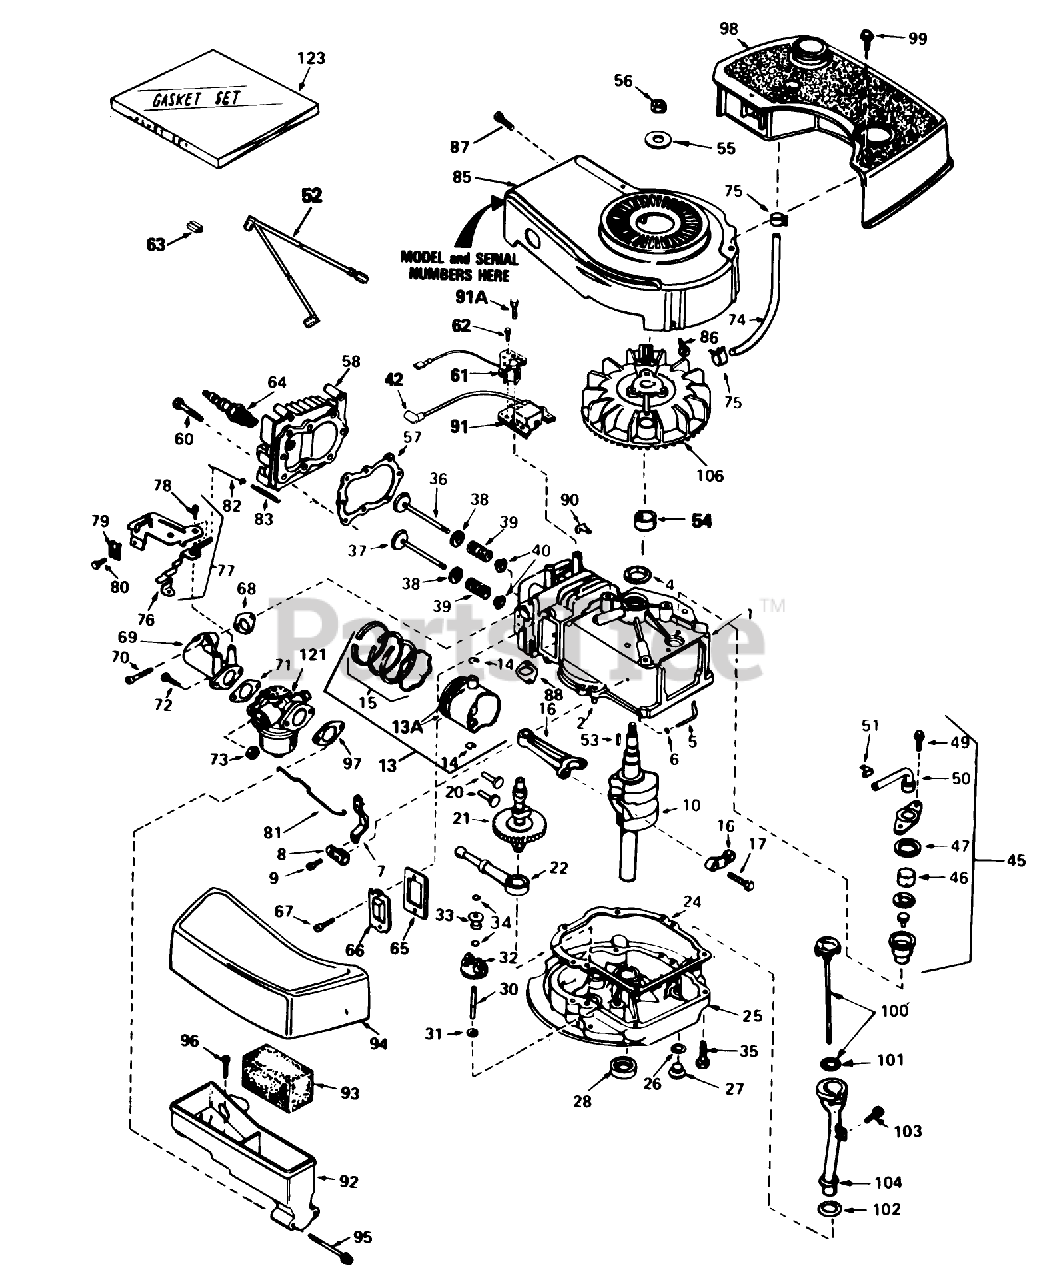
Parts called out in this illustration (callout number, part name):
1	Cyiinder Assy. (Incl. Ref. #2, 4 105)
2	Pin-Dowel
4	Seal-Oil
5	Rod, Governor (Incl. No. 36)
6	Washer-Flat
7	Governor Lever
8	Clamp-Lever, Governor
9	Screw
10	Crankshaft
13	Piston, Pin Ring Assy. (Std.) (Incl. Ref. #13A, 14 15)
13	Piston, Pin Ring Assy. (.010 oversize) (Incl. Ref. #13A, 14 15)
13	Piston, Pin Ring Assy. (.020 oversize) (Incl. Ref. #13A, 14 15)
13A	Piston Pin Assy. (Incl . Ref. . #14) (Std.)
13A	Piston Pin Assy. (Incl. Ref. #14) (.010 Oversize)
13A	Piston Pin Assy. (.020 oversize) (Incl. Ref. #14)
14	Ring-Retaining, Piston Pin
15	Ring Set (Std.)
15	Ring Set (.020" OS)
15	Ring Set (.010" OS)
16	Rod Assy., Connecting (Incl. Ref. #17)
17	Bolt-Rod, Connecting
20	Lifter-Valve
21	Camshaft(Mech.Comp. Release)
22	Oil Pump ASM
24	Gasket, Mounting
25	Flange Assy., Mounting (Incl. Ref. #26thru 30)
26	Gasket-Oil Drain
27	Plug Oil Drain
28	Seal Oil
30	Shaft-Governor
31	Washer-Flat
32	Governor Gear ASM
33	Spool-Governor
34	Ring-Retaining
35	Screw (1/4-20 x 1-1/4)
36	Valve, Intake (Std.) (Incl. Ref. #40)
36	Valve, Intake (1/32" oversize)(Incl. No. 40)
37	Valve, Exhaust (Std.)(Incl. No. 40)
37	Valve, Intake (1/32" oversize)(Incl. No. 40)
38	Cap-Upper Valve Spring
39	Spring-Valve
40	Cap-Valve, Spring
42	Cover-Spark Plug
45	Breather Assy. (Incl. Ref. #46 thru 51)
46	Element-Breather
47	Gasket-Breather
49	Screw (10-24 x 9/16)
50	Tube, Breaker
51	Clip, Breather
52	Wire-Ground
53	Key-Flywheel
54	Spacer
55	Washer-Belleville
56	Nut-Flywheel
57	63573 GIL 42 SNWTHW
58	Head-Cylinder
60	Screw (5/16-18x1-1/2)
61	Coil, Alternator
62	Screw (8-32x27/64)
63	Connector-Body
64	Plug, Spark (J17LM or equiv.)
64	Plug, Spark (Champion RCJ-8)
65	Gasket-Breather
66	Cover-Valve
67	Screw
68	Gasket-Intake
69	Pipe, Intake (Incl. No. 68)
70	Screw (1/4-20 x 1)
71	Gasket-Carburetor
73	Nut and Lock Washer (1/4-28)
74	Line-Fuel
75	Clamp-Line, Fuel
76	Lever Control
77	Control Assy., Speed (Incl. Nos, 76, 78 89)
78	Screw, Hex Washer Hd Shoulder Self-Tap
79	Conduit
80	Screw (10-32 x 3/8)
81	Link-Throttle
82	Link Governor Spring
83	Spring Governor
85	Housing-Blower
86	Screw (1/4-20x19/32)
87	Screw (10-24 x 9/16)
88	Gasket Exhaust
90	Clip-Wire
91	Solid State
91A	Screw
92	Body Air Cleaner
93	Filer, Air
94	Cove, Air Cleaner
95	Screw Fil Hd.
96	Screw, Hex Hd.
97	Gasket-Air Cleaner
98	Tank-Fuel
99	Screw (10-32 x 35/64)
100	Dipstick, Oil (Incl. Ref. #101)(Twist Lock)
101	O-Ring
102	Gasket
103	Screw (10-32 x 1/2)
104	Tube-Oil Fill
106	Flywheel
121	Carburetor (Incl. Ref. #71)
123	Gasket Set
